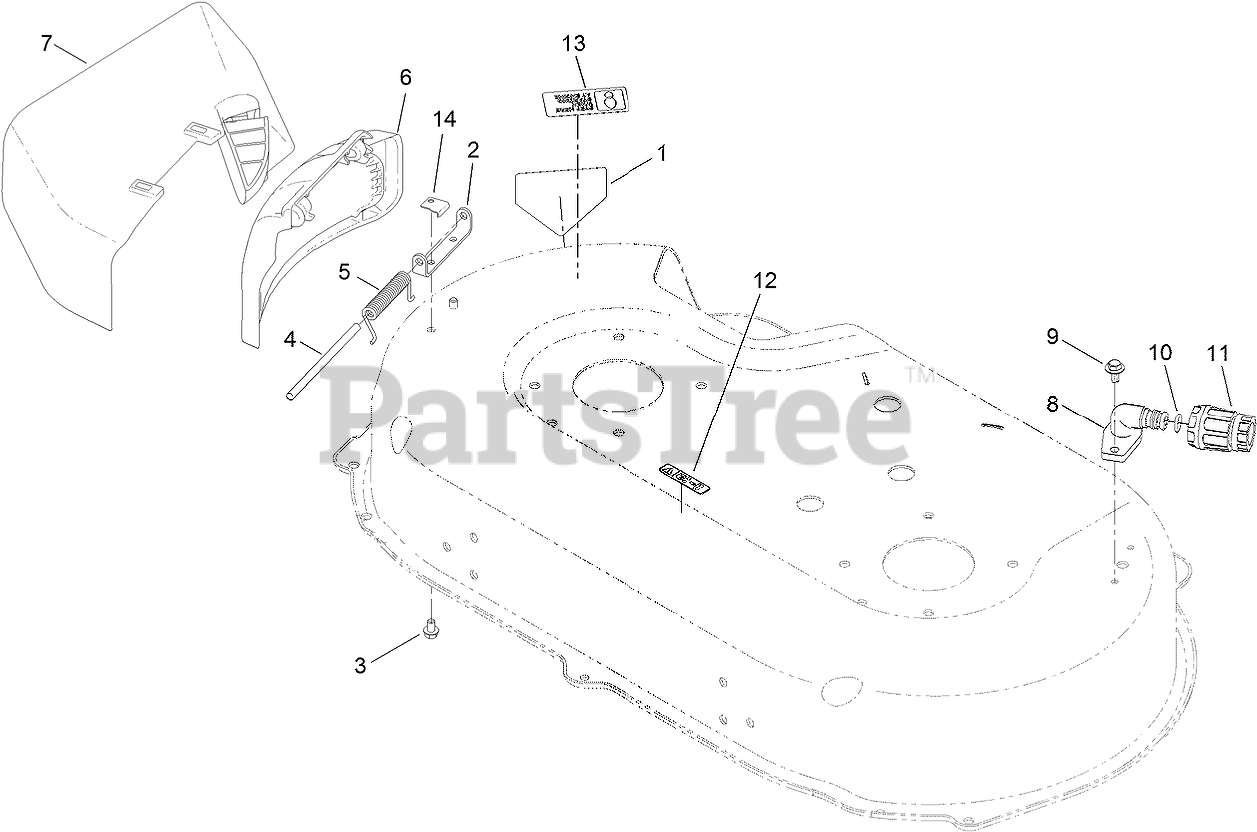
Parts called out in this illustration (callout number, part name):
1	DECAL-DANGER
2	BRACKET-COVER
3	SCREW-HWH
4	ROD-COVER
5	SPRING-TORSION, COVER
6	DEFLECTOR-SIDE
7	CHUTE-DISCHARGE, SIDE
8	FITTING-WASHOUT
9	SCREW-HHFTF
10	O-RING
11	CONNECTOR-HOSE
12	DECAL-WARNING
13	DECAL-PLACEMENT, FOOT
14	PLATE-SPRING
